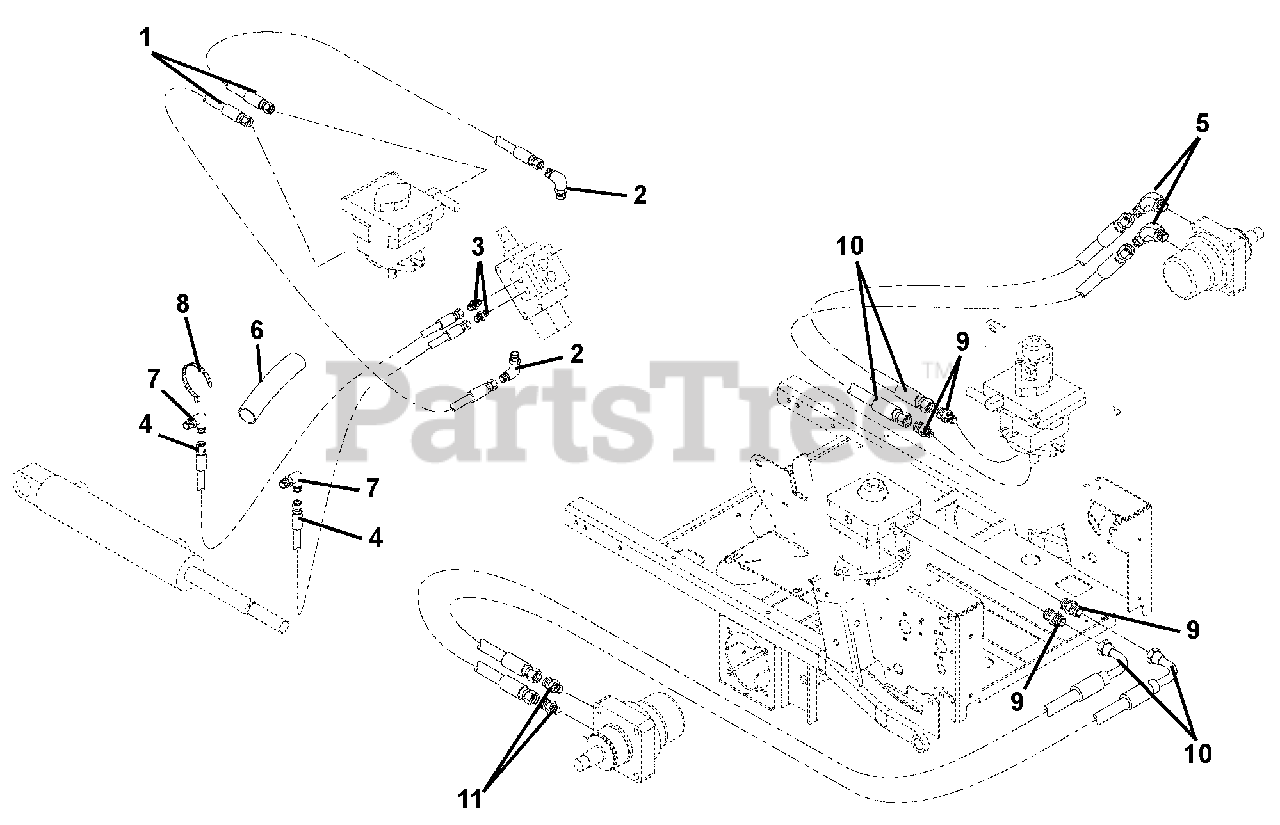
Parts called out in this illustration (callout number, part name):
1	Hose, Hydraulic
2	Hydraulic, Fitting Elbow
3	Adapter (4-6F5OLO)
4	Hose, Hydraulic
5	Fitting, Hydraulic (8-10 V5OLO)
6	Sleeve, Protective 24 in.
7	Fitting, Hydraulic (4 C5OLO)
8	Cable Tie
9	Adapter, Face Seal 8 x 8 .50 O-Ring
10	Hose, Hydraulic .50
11	Adapter, Hydraulic Steel (M10 O-M8F)
